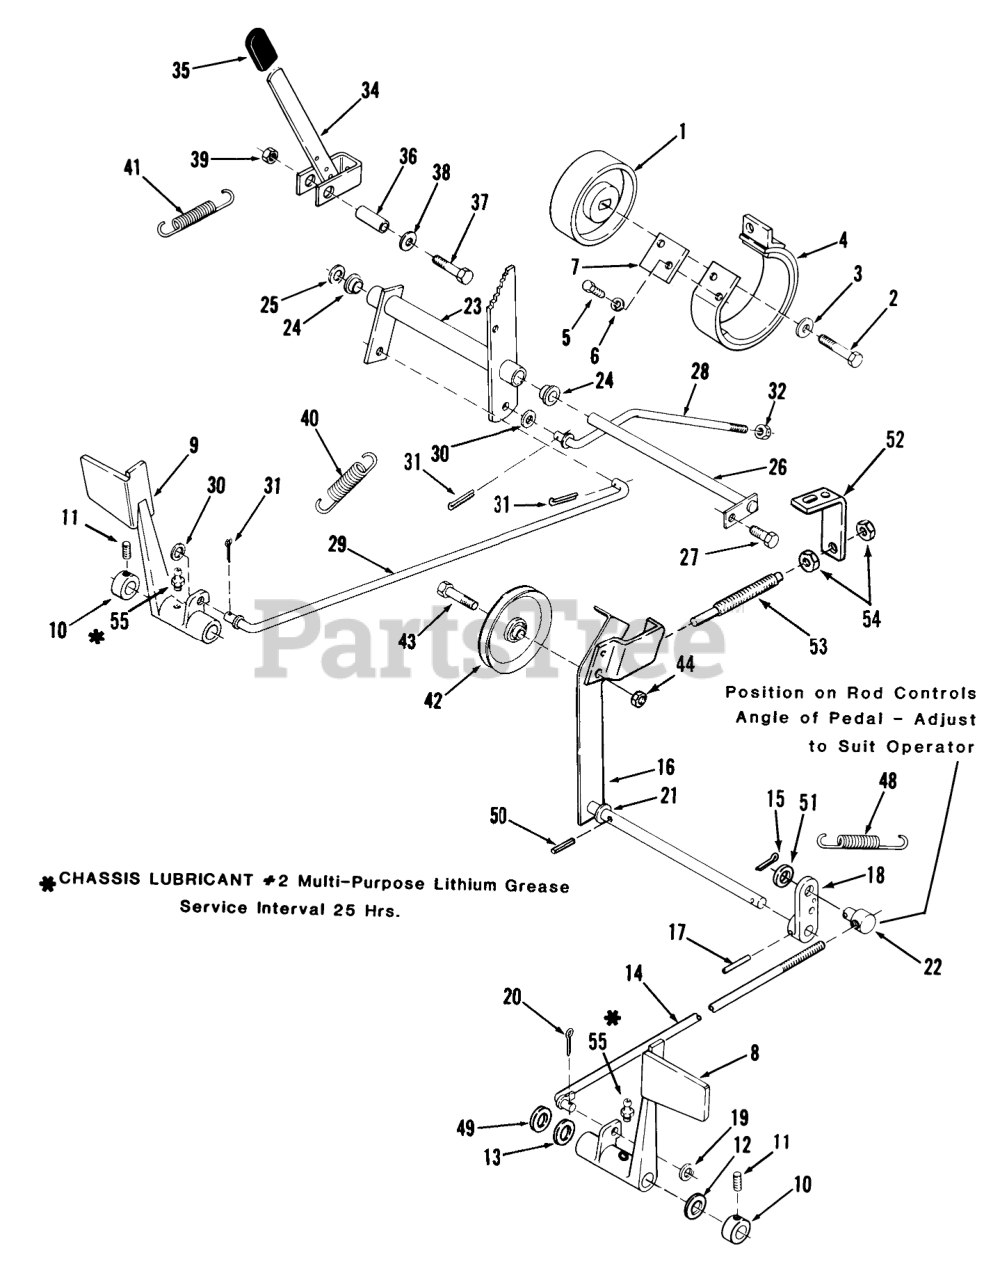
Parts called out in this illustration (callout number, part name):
1	DRUM-BRAKE
2	SCREW-HEX HD CAP
3	WASHER
4	BRAKE BAND ASM
5	H H C S
6	Washer
7	Plate-Stop
8	PEDAL-CLUTCH R
9	Pedal-Brake
10	Collar
11	SCREW-SET
12	WASHER-BOWED
13	WASHER
14	ROD AND GUIDE ASM
15	Cotter Pin
16	ASS'Y-IDLER ARM R
17	PIN-SPIROL
18	Arm-Clutch Rod
19	WASHER-NYLON
20	Pop Rivet
21	SHIM-WASHER
22	TRUNNION
23	Bellcrank Assy
24	BUSHING-FLANGED
25	Washer
26	ROD ASM
27	SCREW
28	ROD-REAR BRAKE
30	WASHER-NYLON
31	Pop Rivet
32	NUT
34	ASSY-BRAKE LEVER WAB
35	GRIP
36	SPACER
37	Bolt
38	Washer
39	LOCKNUT-FLANGE
40	SPRING-BRAKE
41	SPRING-EXTENSION
42	PULLEY-IDLER
43	BOLT-SPECIAL HEX
44	NUT
48	SPRING-CLUTCH
49	Washer
50	PIN-SPIROL
51	Washer
52	BRKT-DAMPER B
53	Damper Cylinder
54	Nut
55	Zerk
